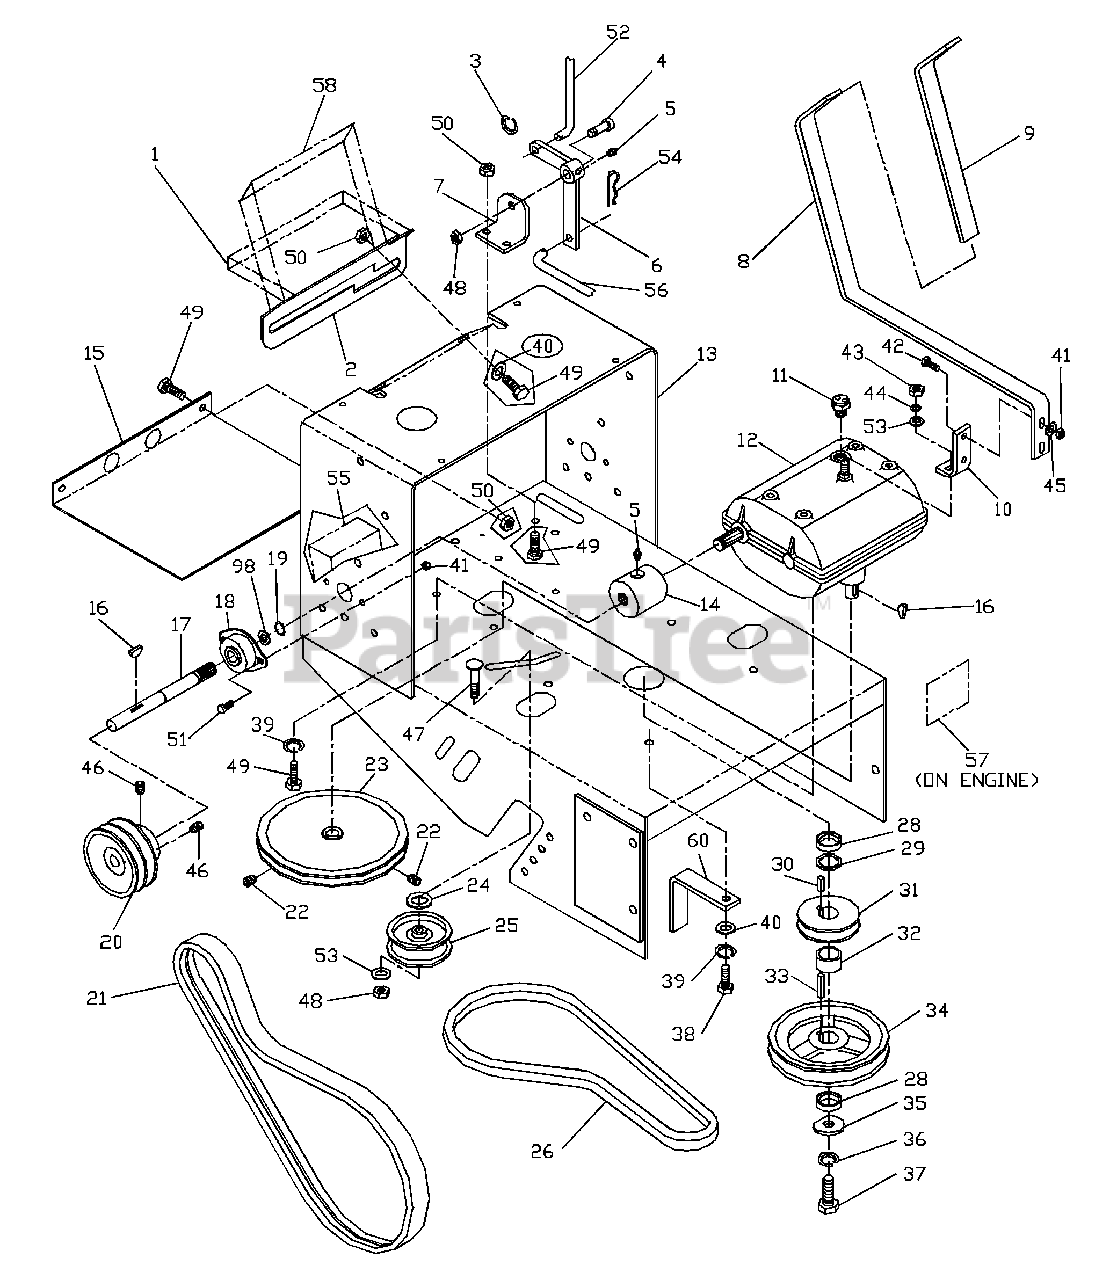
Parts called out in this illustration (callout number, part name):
1	DECAL,SHIFTER
2	SHIFTER PLATE
4	SB 1/2C X 3/4
5	ZERK1/4-28 STRHT
8	SHIFTER ARM
9	SHIFTER GRIP
10	SHIFTER BRKT.
11	TRANS. SWITCH
12	TRANSMISSION
13	REAR DECK W/DECALS
15	LOWER BELT SHIELD
16	#9 WOODRUFF KEY
17	DRIVE SHAFT
19	RETAINER RING
20	DRIVE PULLEY(36&48)
20	DRIVE PULLEY(32)
21	DRIVE BELT(36&48)
21	DRIVE BELT(32)
22	1/4-20 NYLOC SETSCW.
23	INPUT PULLEY
24	1/2 FLAT WASHER STD
25	IDLER PULLEY
26	BELT, TRANSMISSION
27	BELT GUIDE(NOT SHN.)
29	MACH. BUSHING
30	KEY 1/4SQ. X 3/4
33	KEY 1/4SQ. X 1 1/8
34	ENGINE PULLEY
35	CRANKSHAFT WASHER
36	SLW 7/16 STD
37	HCS M10-1.5 X 35MM (Kawasaki)
37	HCS 7/16F X 1.5 GR 5 (Kohler)
38	HTB M8-1.25 X 35MM (Kawasaki)
38	HCS M8-1.25 X 30MM (Kohler)
39	SLW 5/16 STD
40	5/16 FW STD
42	HCS 1/4C X 1
44	SLW 3/8 STD
45	FW 1/4 STD
46	5/16 NYLOC SETSCW
46	(32" MODELS)
47	RHSNB 3/8C X 2
48	HLN 3/8C CENTER P.
49	HCS 5/16C X 3/4
51	HCS 1/4C X 5/8
53	FW 3/8 STD
54	#4 HAIRPIN
55	DANGER DECAL
56	BLADE ROD 48"
56	BLADE ROD 36"
57	EXHAUST DECAL
58	DECAL, CLUTCH
59	MACH. BUSHING
60	BELT GUIDE,LONG
60	48" MODELS
60	32" & 36" MODELS
